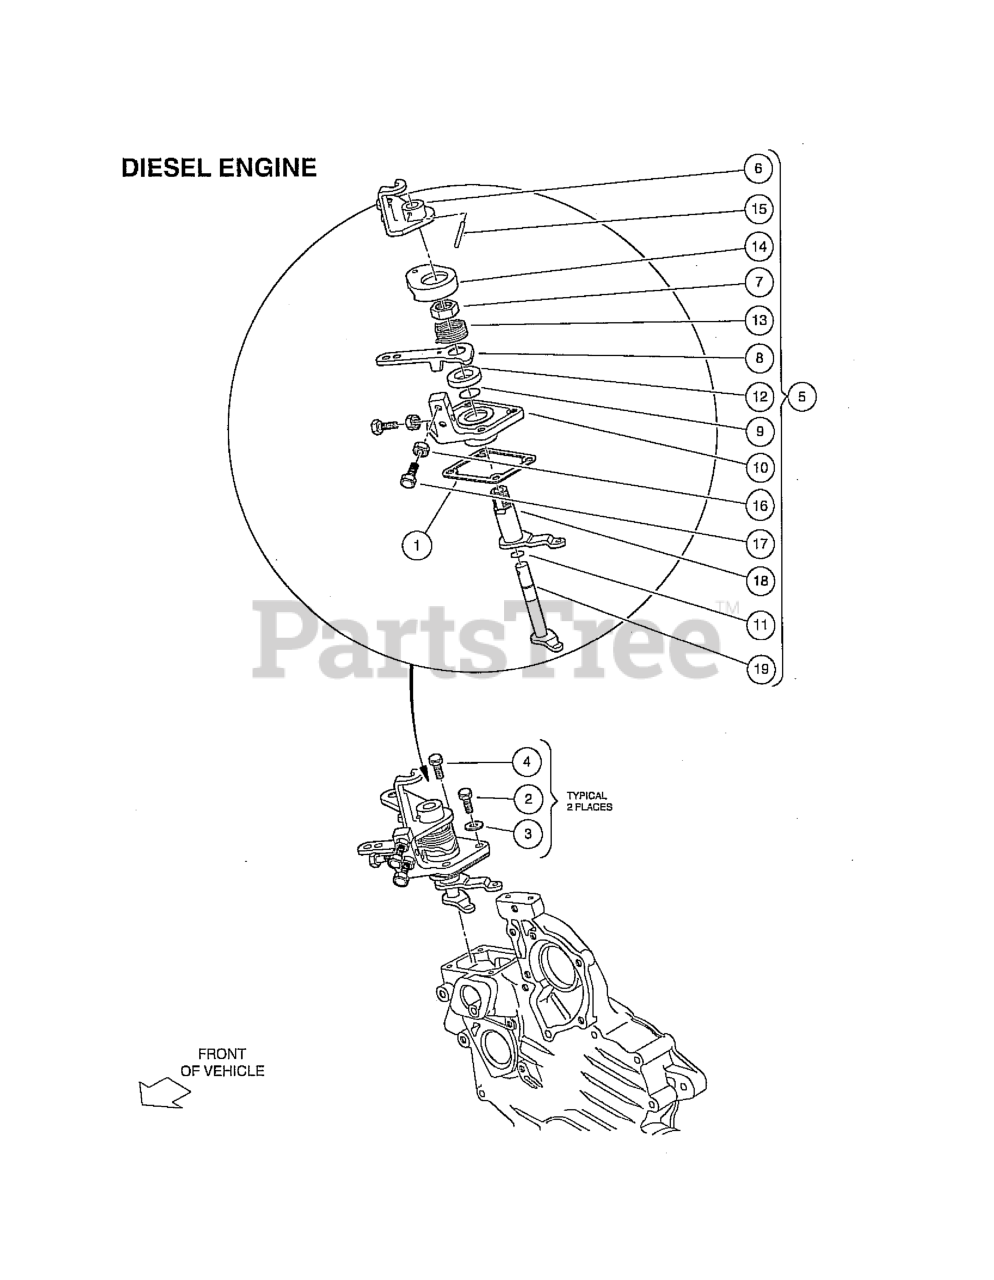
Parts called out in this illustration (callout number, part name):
1	GASKET, CONTROL PLATE
2	BOLT, M6X1X30
3	GASKET, 6X10
4	BOLT, D722 INTAKE MANFLD LOWER
5	ASSY-SPEED PLATE
6	LEVER, ENGINE STOP
7	NUT, SPEED CONTROL
8	LEVER, SPEED CONTROL
9	O RING, 19X16
10	PLATE, SPEED CONTROL
11	O RING, 9X7
12	COLLAR, LEVER
13	SPRING, RETURN
14	CAP, SPEED CNTRL PLATE RTRN
15	PIN, SPRING, SPEED PLATE
18	LEVER-GOVERNOR
